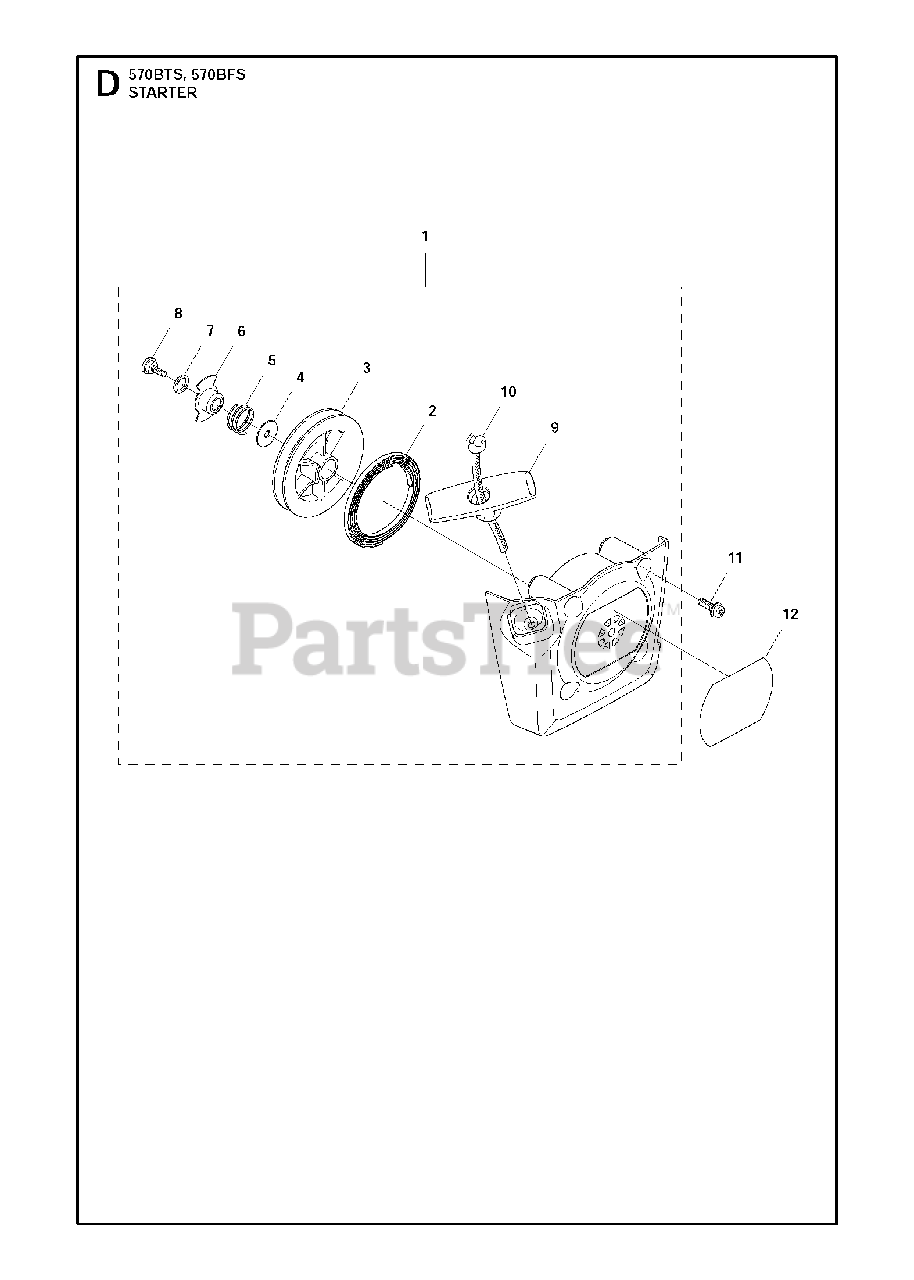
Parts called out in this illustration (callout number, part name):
1	STARTER ASSY
2	SPRING
3	REEL
4	WASHER
5	SPRING FRICTION
6	PLATE
7	WASHER
8	SCREW
9	HANDLE
10	ROPE
12	DECAL, RECOIL
12	DECAL RECOIL
